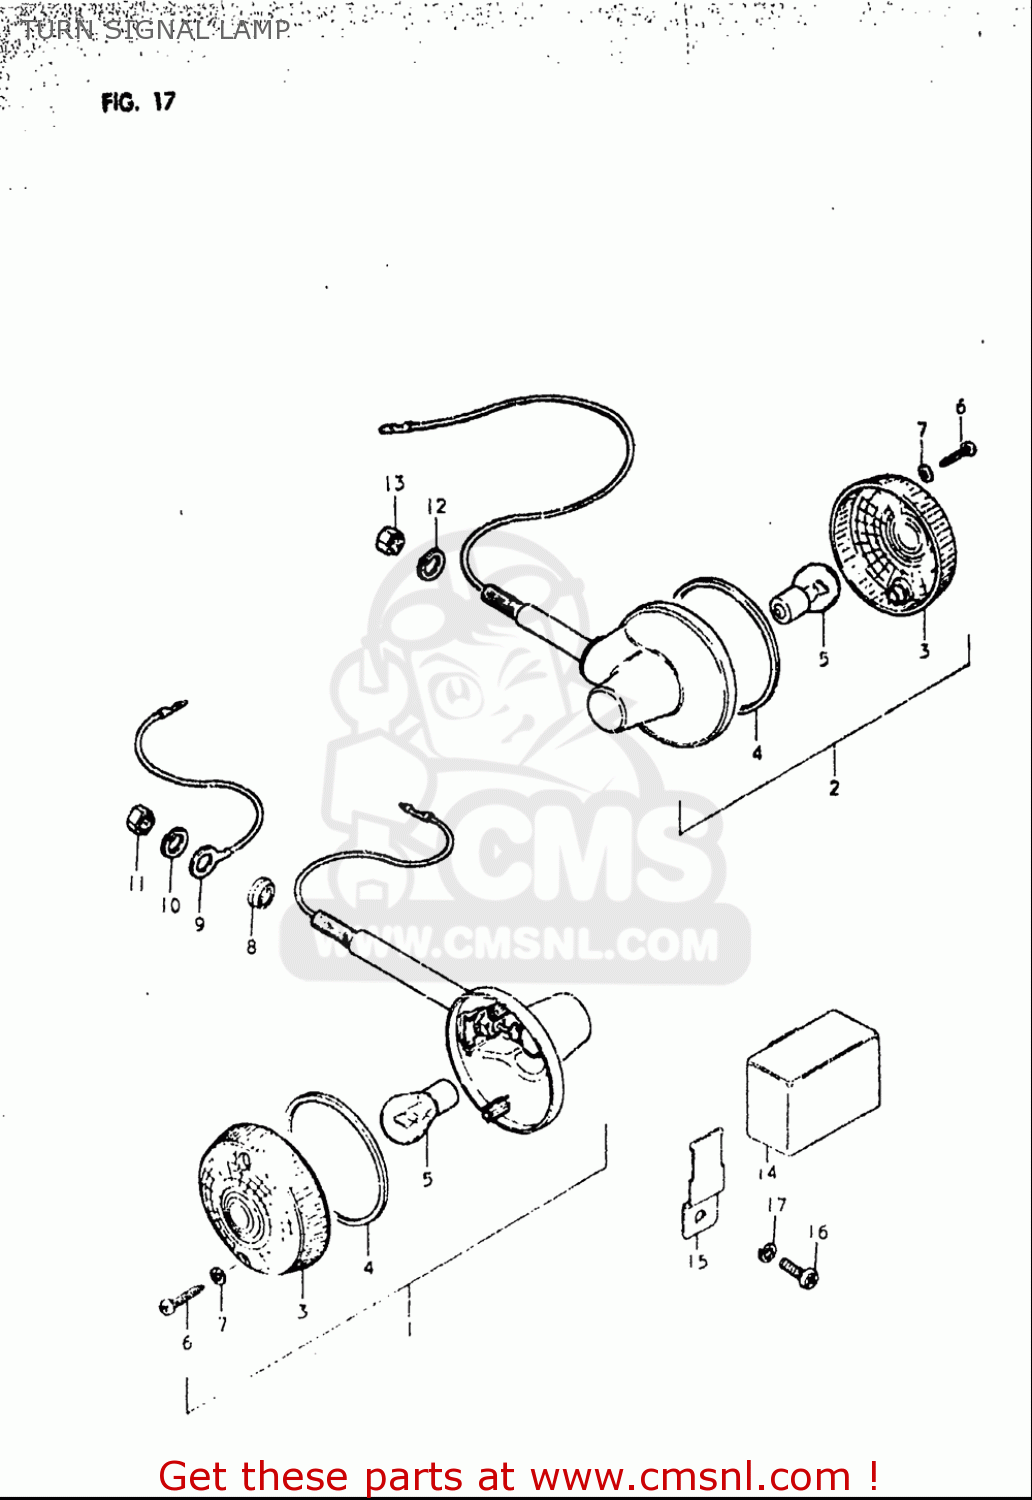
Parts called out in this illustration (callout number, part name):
2	LAMP ASSEMBLY,REAR TURN SIGNAL
3	LENS
4	GASKET (NAS)
5	BULB(6V17W,STANLEY,A4513A)
6	SCREW
7	GASKET (NAS)
9	LEAD WIRE,EARTH
10	WASHER,LOCK
11	NUT
12	WASHER,LOCK
13	NUT
14	RELAY ASSY,TURNSIGNAL
15	BRACKET,TURN SIGNAL RELAY
16	SCREW
17	WASHER,LOCK
